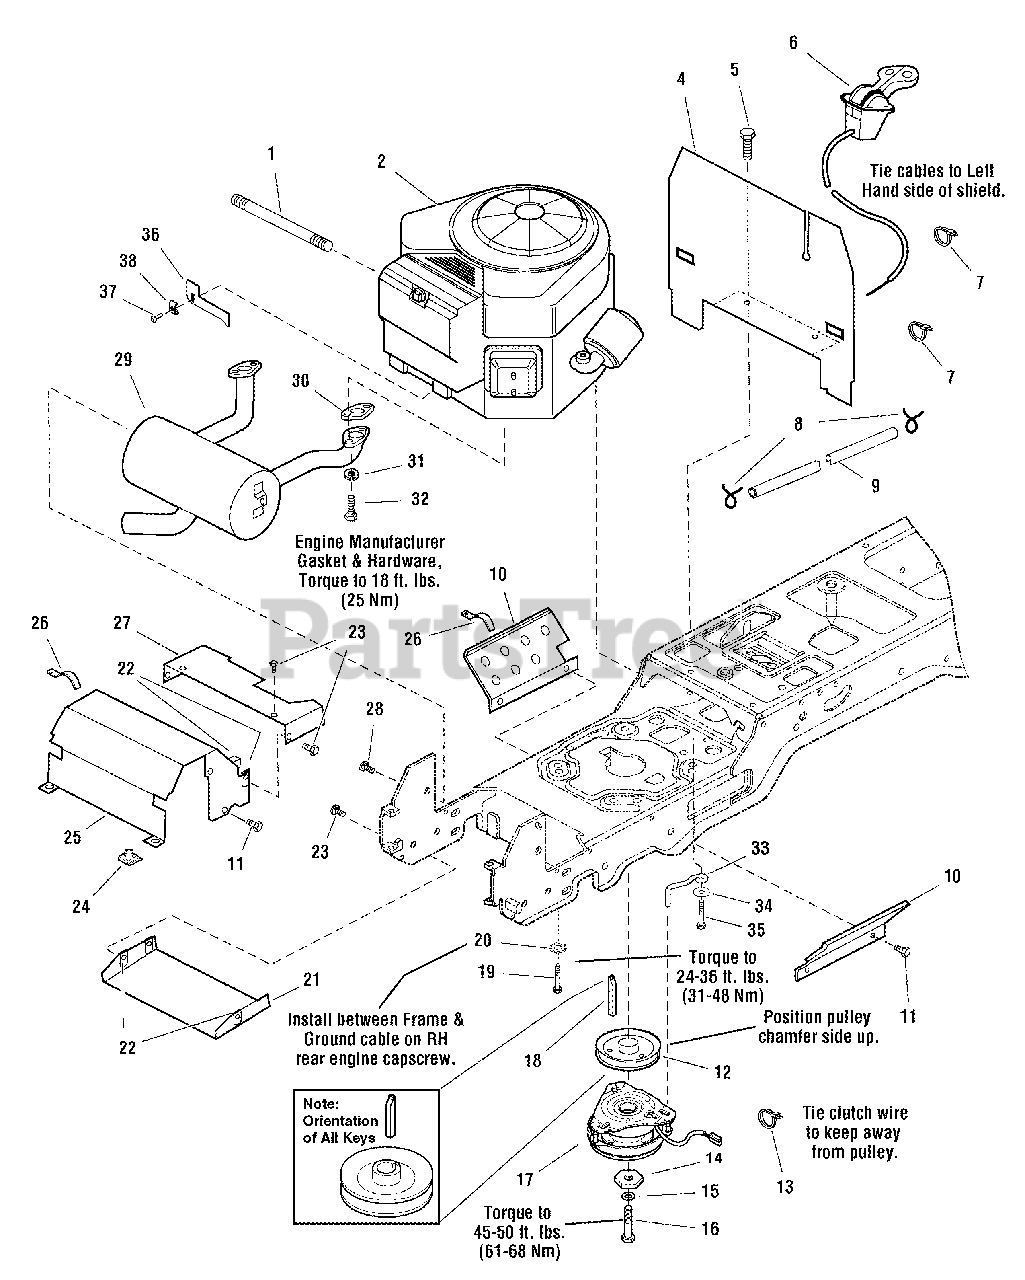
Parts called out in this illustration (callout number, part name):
1	HOSE, Oil Drain, 10-1/2" Long, 3/8-18 Fittings
2	* ENGINE, 21HP B&S Vanguard Twin, Mod. 385777-0119-G1
4	BULKHEAD
5	CAPSCREW, Hex Washer Head Taptite, 1/2-20 x 1/2, Black
6	CONTROL, Throttle Double 39" Long w/Knobs
7	TIE, Wire, 7-5/16" Long
8	CLAMP, Hose
9	HOSE, Fuel, 59" Long
10	SHIELD, Side
11	CAPSCREW, Hex Washer Head Taptite, 1/4-20 x 3/8
12	PULLEY & HUB ASSEMBLY
13	TIE, Self Locking, 3-5/8 Long
14	WASHER, Hex, 7/16, Black
15	LOCKWASHER, 7/16
16	CAPSCREW, Hex Head, 7/16-20 x 3-3/4
16	PLATE, FOOT REST - RED
17	CLUTCH, Electric
17	WELD, PLATE, SEAT MOUNT - RED
18	KEY, HI PRO, 1/4 x 2 1/2
19	CAPSCREW, Hex Washer Head Taptite, 3/8-16 x 1-1/2
20	LOCKWASHER, External Tooth, 3/8
21	SHIELD, Muffler Bottom
22	NUT, Speed, 1/4-20, Lug
23	CAPSCREW, Hex Flange Whiz Lock, 1/4-20 x 5/8
24	NUT, Speed, Lug Type, 5/16-18
25	DUCT, Muffler Top
26	CLIP, Wire 1/8
27	DUCT, Muffler Extension
28	CAPSCREW, Hex Washer Head Taptite, 5/16-18 x 1/2, Black
29	MUFFLER, Briggs & Stratton, Vanguard Twin
30	* GASKET, Briggs & Stratton, Vanguard Twin
33	RETAINER, Clutch
34	WASHER, Flat 3/8
35	CAPSCREW, 3/8-16 x 1
38	THROTTLE CABLE - Clamp
